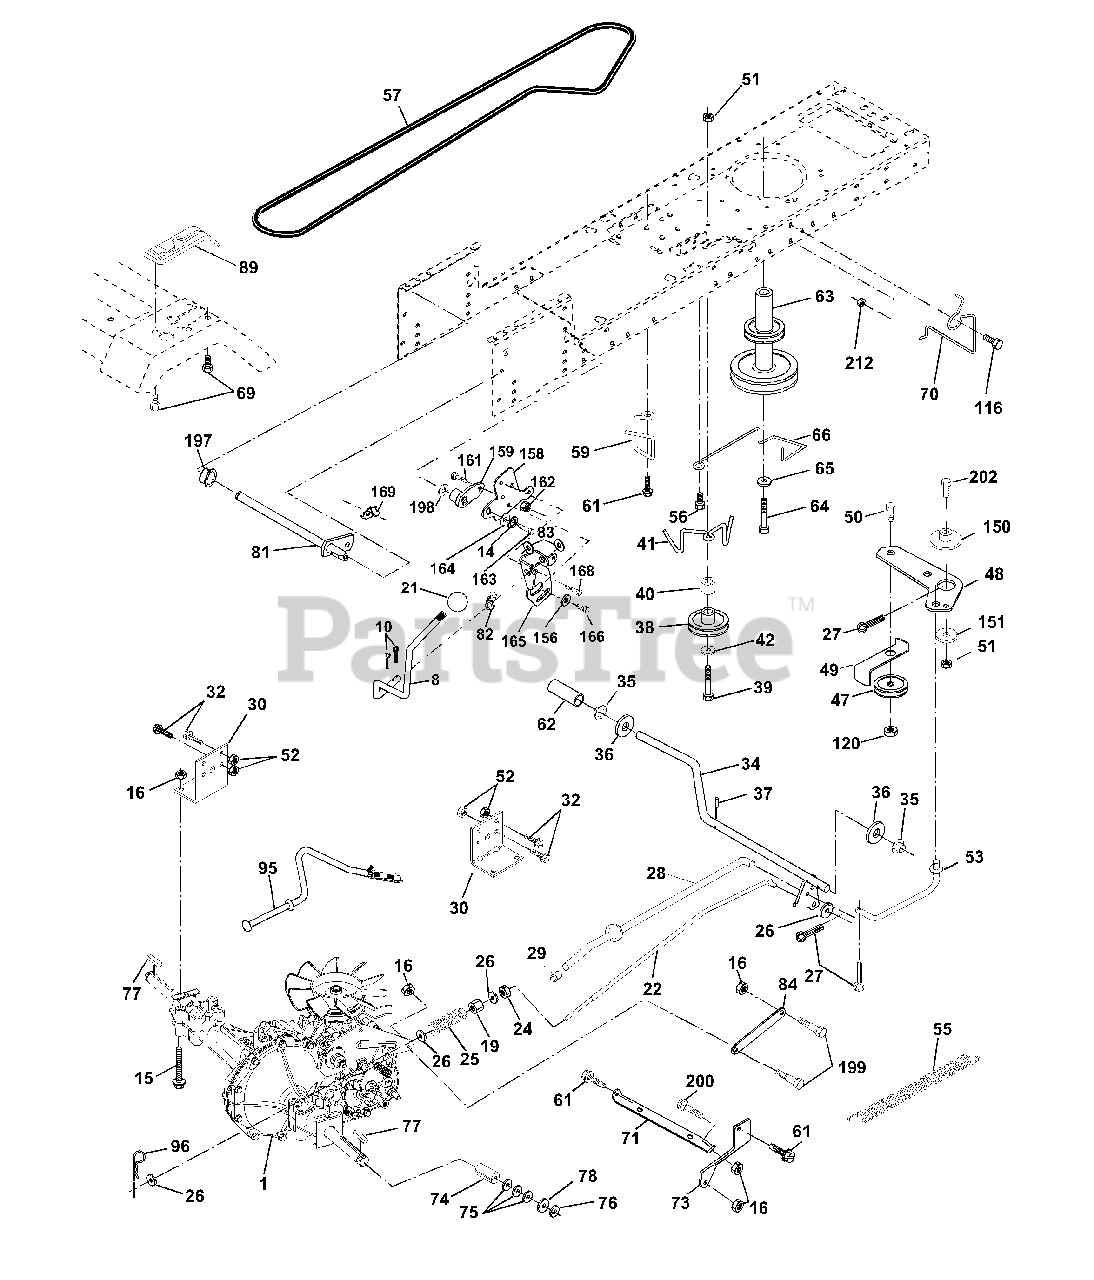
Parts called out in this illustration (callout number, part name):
8	Rod Shift Hydro LT
10	Pin Cotter 1/8 x 1 CAD
14	Washer Lock Hvy Helical
15	Bolt, Hex FLGHD 5/16-18 Gr. 5
16	Nut Lock Hex W/Ins 5/16-18 Unc P
19	Nut Lock Hex W/Wsh 3/8-16 Unc
21	Knob, Round 1/2-13
22	Rod, Brake Hydro
24	Nut
25	Spring, Brake Rod
26	Washer
27	Pin Cotter 1/8 x 3/4 CAD.
28	Rod, Parking Brake
29	Cap, Parking Brake
30	Bracket, Transaxle
32	Bolt Hex Hd 5/16-18 Unc x 3/4
34	Shaft, Foot Pedal Nibbed
35	Bearing, Nylon
36	Washer
37	Pin, Roll
38	Pulley, Composite, Flat
39	Bolt
40	Spacer, Split
41	Keeper, Belt Idler
42	Washer 13/32 x 13/16 x 12 Gauge
47	Pulley, Idler, V-Groove
48	Bellcrank Clutch Grnd Drv STL
49	Retainer, Belt
50	Bolt
51	Nut Crownlock 3/8-16 UNC
52	Nut Crownlock 5/16-18 UNC
53	Link, Clutch
55	Spring, Return, Clutch
56	Bolt Fin Hex 3/8-16 UNC x 1-1/4
57	V-Belt, Ground Drive
59	Keeper, Center Span
61	Screw Thdrol. 3/8-16 x .75
62	Cover, Pedal
63	Pulley, Engine
64	Bolt, Hex
65	Washer
66	Keeper Belt Engine
69	Screw
70	Guide Belt
71	Strap Torque Lh Hydro
73	Strap Torque Rh Hydro
74	Spacer, Axle
75	Washer 25/32 x 1-1/4 x 16 Gauge
76	E-Ring
77	Key, Square
78	Washer 25/32 x 1-5/8 x 16 Gauge
81	Shaft Asm. Cross Hydro
82	Spring Torsion T/A
83	Washer 17/32 x 3/4 x 16 Ga.
84	Link Transaxle
89	Console, Hydro
95	Control Asm Bypass Hydro
96	Retainer Spring 1" Zinc/Cad
116	Bolt Rdhd Sq Neck 3/8-16 x 1
120	Nut Lock Flg. 3/8-16
150	Spacer Retainer
151	Washer 13/32 x 2 x 10 Ga.
156	Washer Srrted 5/16 ID x 1.125
158	Bracket Shift Mount
159	Hub Tapered Flange Shift Lt
161	Bolt Rdhd Sqnk 1/4-20 x 3/4 Gr 5
162	Nut Crownlock 1/4-20 Unc
163	Bolt Hex Fin 1/4-20 Unc x 1 Gr 5
164	Washer 5/8 x .281 x 10 Ga
165	Bracket Pivot Lever
166	Screw 5/16-18 x 5/8
168	Bolt Shoulder 5/16-18 x .561
169	Plate Fastening Lt
197	Nyliner Snap-In 5/8" ID
198	Washer Nyl 7/8 ID x .105
199	Bolt Shoulder 5/16-18 Unc
200	Bolt Rdhd Sqnk 5/16-18 Unc x 1
202	Bolt Carr Sh 3/8-16 x 1-1/2 Gr 5
212	Nut Hex Flange Lock
